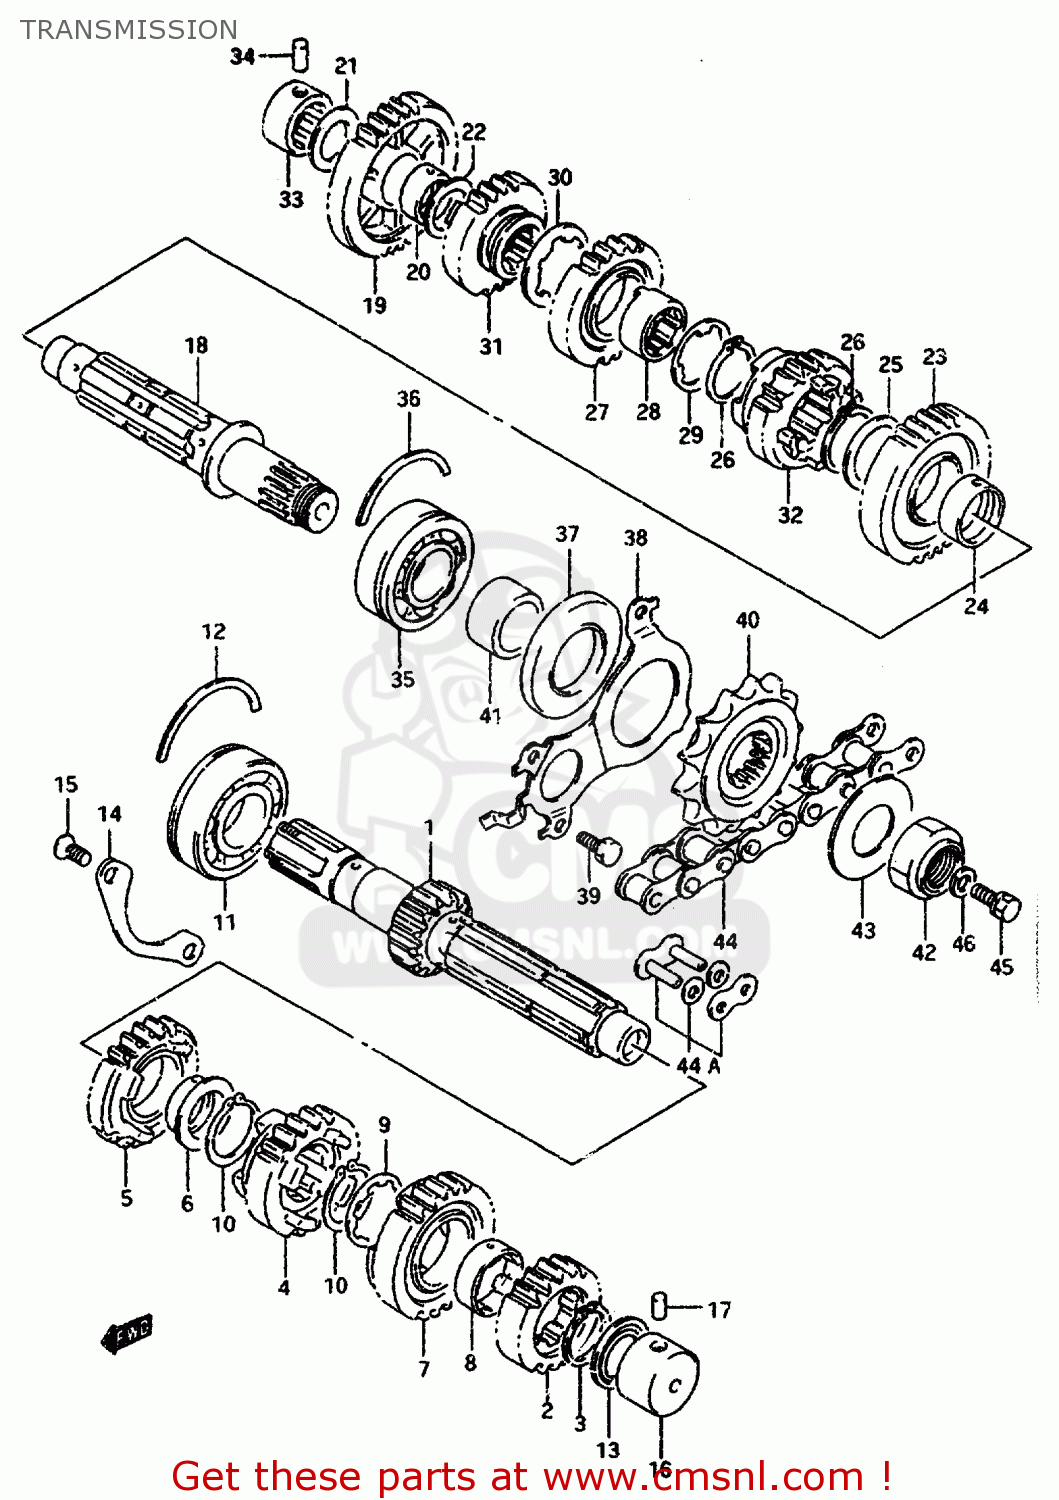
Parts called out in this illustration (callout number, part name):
1	SHAFT COMP,COUNTER
2	GEAR,2ND DRIVE
3	CIRCLIP
4	GEAR,THIRD DRIVE
5	GEAR,FOURTH DRIVE
6	BUSH(28X32X2)
7	GEAR,FIFTH DRIVE
8	BUSH
9	WASHER,LOCK
10	CIRCLIP
11	BEARING(25X62X17)
12	C RING
13	SEAL,OIL(20X31.2X2.7)
14	RETAINER,CNTR SHAFT BEARING
15	SCREW
16	BEARING
17	PIN
18	SHAFT,DRIVE
19	GEAR,1ST DRIVEN
20	BUSHING
21	WASHER
22	WASHER
23	GEAR,2ND DRIVEN
24	BUSH(28X32X11)
25	SHIM(28X38X1)
26	CIRCLIP
27	GEAR,3RD DRIVEN
28	BUSHING,THIRD DRIVEN GEAR
29	WASHER,LOCK
30	WASHER,LOCK
31	GEAR,4TH DRIVEN
32	GEAR,5TH DRIVEN
33	BEARING(20X34X20)
34	PIN
35	BEARING(28X70X18)
36	C RING
37	SEAL,OIL(34.8X70X6)
38	RETAINER,DRIVE SHAFT OIL SEAL
39	BOLT
40	SPROCKET,ENGINE(15T)
41	SPACER(25X36X17.7)
42	NUT
43	WASHER,THRUST
44	CHAIN,DRIVE(116LE)
44A	JOINT SET
45	BOLT
46	WASHER
